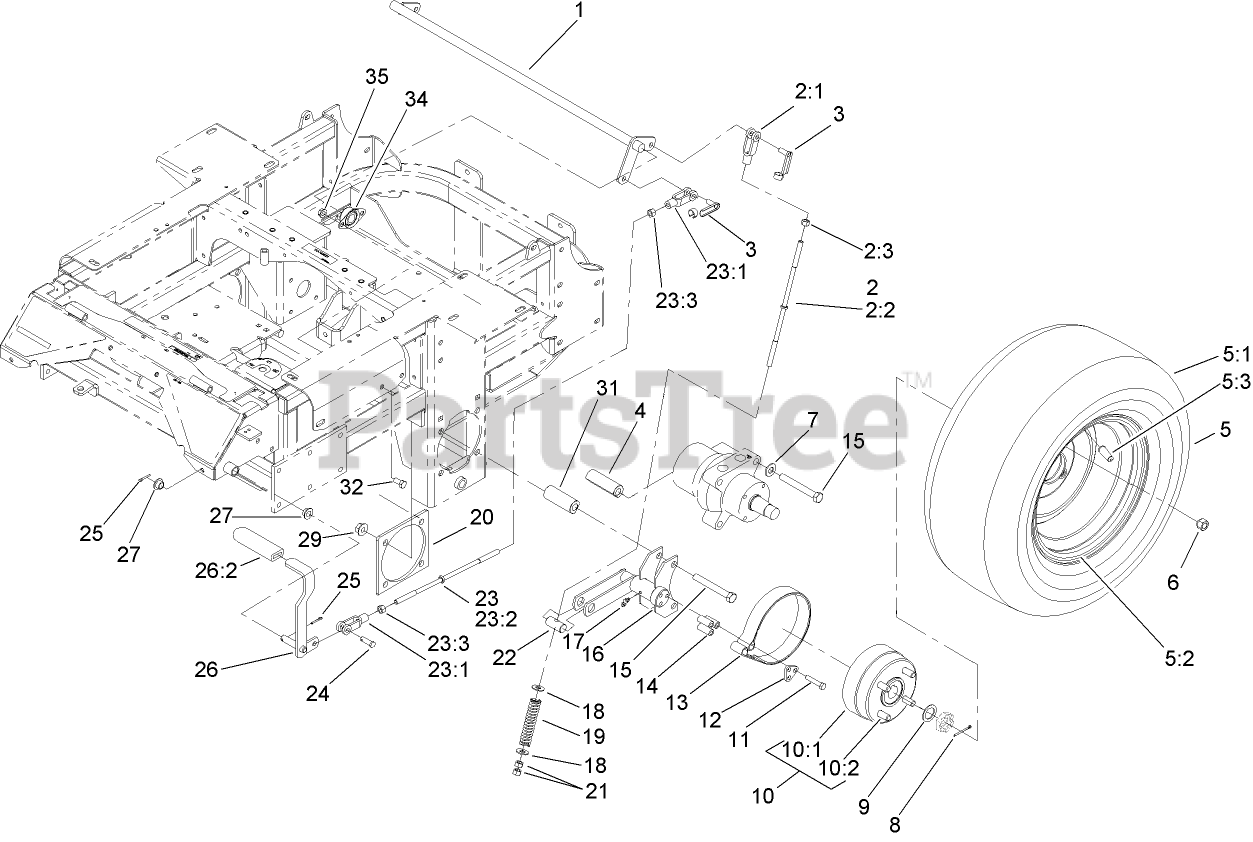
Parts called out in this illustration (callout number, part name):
1	SHAFT-BRAKE
2	BRAKE ROD ASM
2:1	YOKE-LINKAGE, BRAKE
2:2	ROD-BRAKE
2:3	NUT-HEX
3	Pin-Spring, Clevis
4	SPACER-WHEEL, LONG
5	WHEEL AND TIRE ASM
5:2	WHEEL RIM
5:3	STEM-VALVE
6	NUT-LUG
7	WASHER-THRUST
8	PIN-COTTER
9	WASHER-SPACER
10	WHEEL HUB ASM
10:1	HUB-WHEEL
10:2	STUD-WHEEL
11	SCREW-HH
12	RETAINER-BAND, BRAKE
13	BAND-BRAKE
14	SPACER
15	SCREW-HH
16	BRAKE BRACKET ASM
17	FITTING-GREASE
18	WASHER-FLAT
19	SPRING-BRAKE
20	PLATE-REINFORCEMENT
21	NUT-HEX
22	PIN-TRUNION
23	BRAKE ROD ASM
23:1	YOKE-LINKAGE, BRAKE
23:2	ROD-BRAKE
23:3	NUT-HEX
24	PIN-CLEVIS
25	PIN-COTTER
26	BRAKE LEVER ASM
26:2	GRIP-LEVER
27	BEARING-CONTROL
29	NUT-HHF
31	SPACER-WHEEL, SHORT
32	SCREW-HH
34	BEARING-FLANGE, SIDE
35	NUT-HHF, WHIZ
